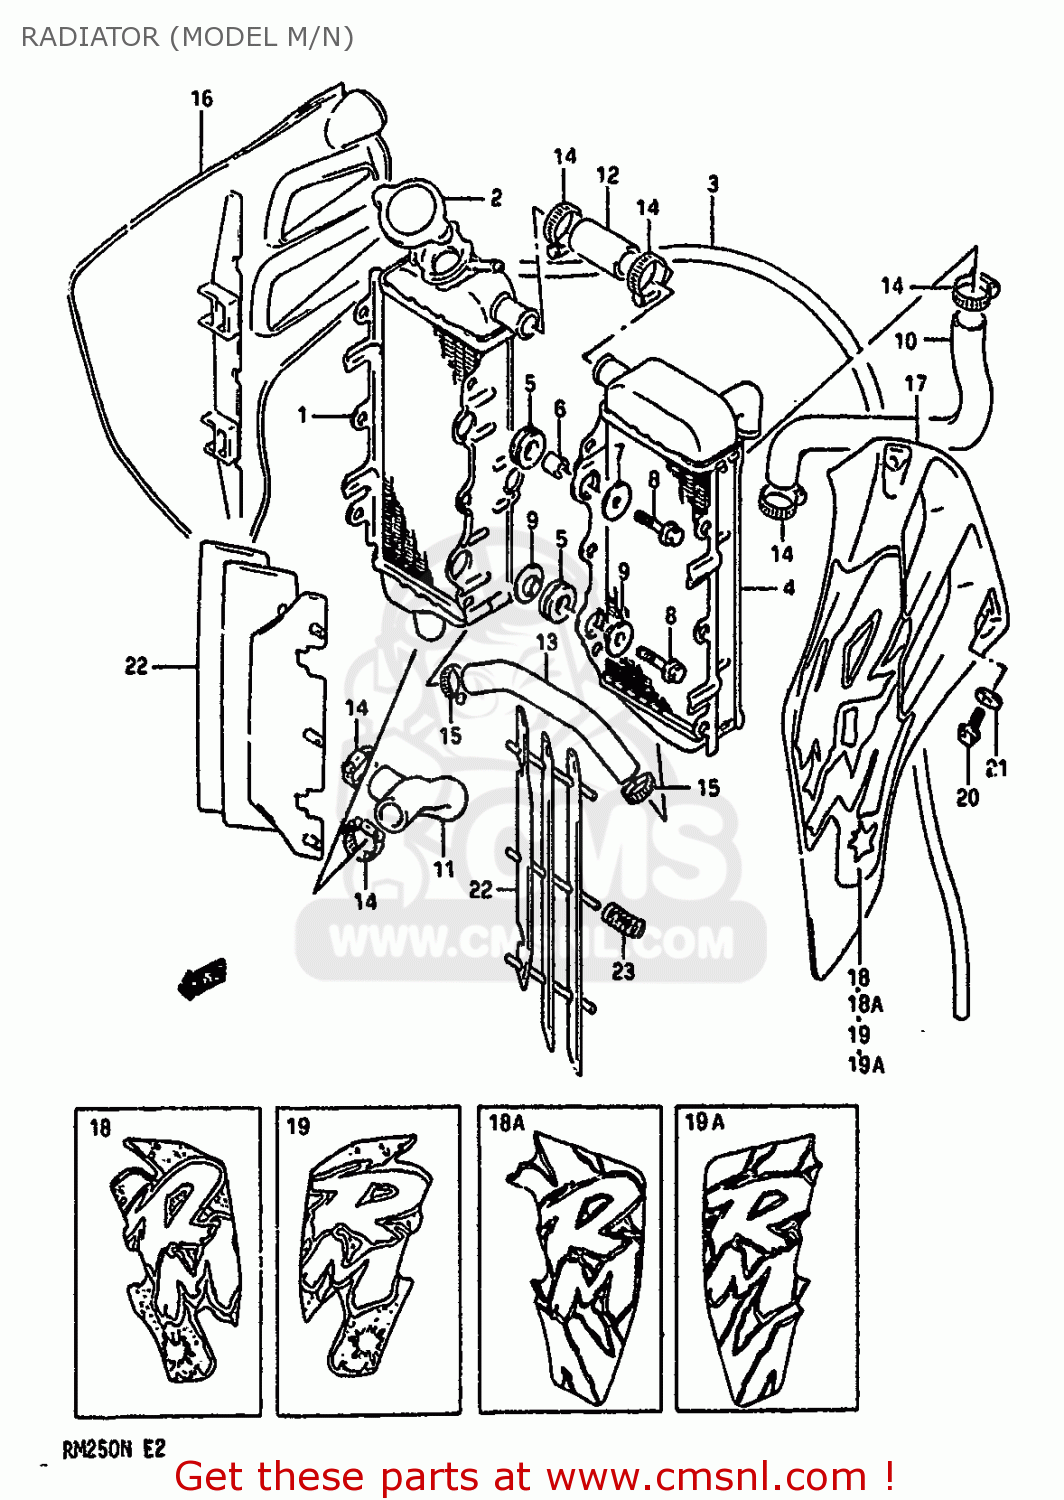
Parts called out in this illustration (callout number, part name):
1	RADIATOR,WATER,R
2	CAP,RADIATOR 1.1
3	HOSE
4	RADIATOR,WATER,L
5	CUSHION,RADIATOR LWR
6	SPACER(6.5X10.5X12)
7	WASHER (6.5X24X1.2)
8	BOLT
9	WASHER,RDTR SPRT
10	HOSE,RADIATOR INLET
11	HOSE,RADIATOR OUTLET
12	HOSE,RADIATOR JOINT NO.1
13	HOSE,RADIATOR JOINT NO.2
14	CLAMP
15	CLAMP
16	COVER,RADIATOR,R
17	COVER,RADIATOR,L
18	EMBLEM,RADIATOR COVER RH
18A	EMBLEM,RADIATOR COVER RH
19	EMBLEM,RADIATOR COVER LH
19A	EMBLEM,RADIATOR COVER LH
20	BOLT
21	SPRING
22	CLAMP(L:165)
23	SPRING
